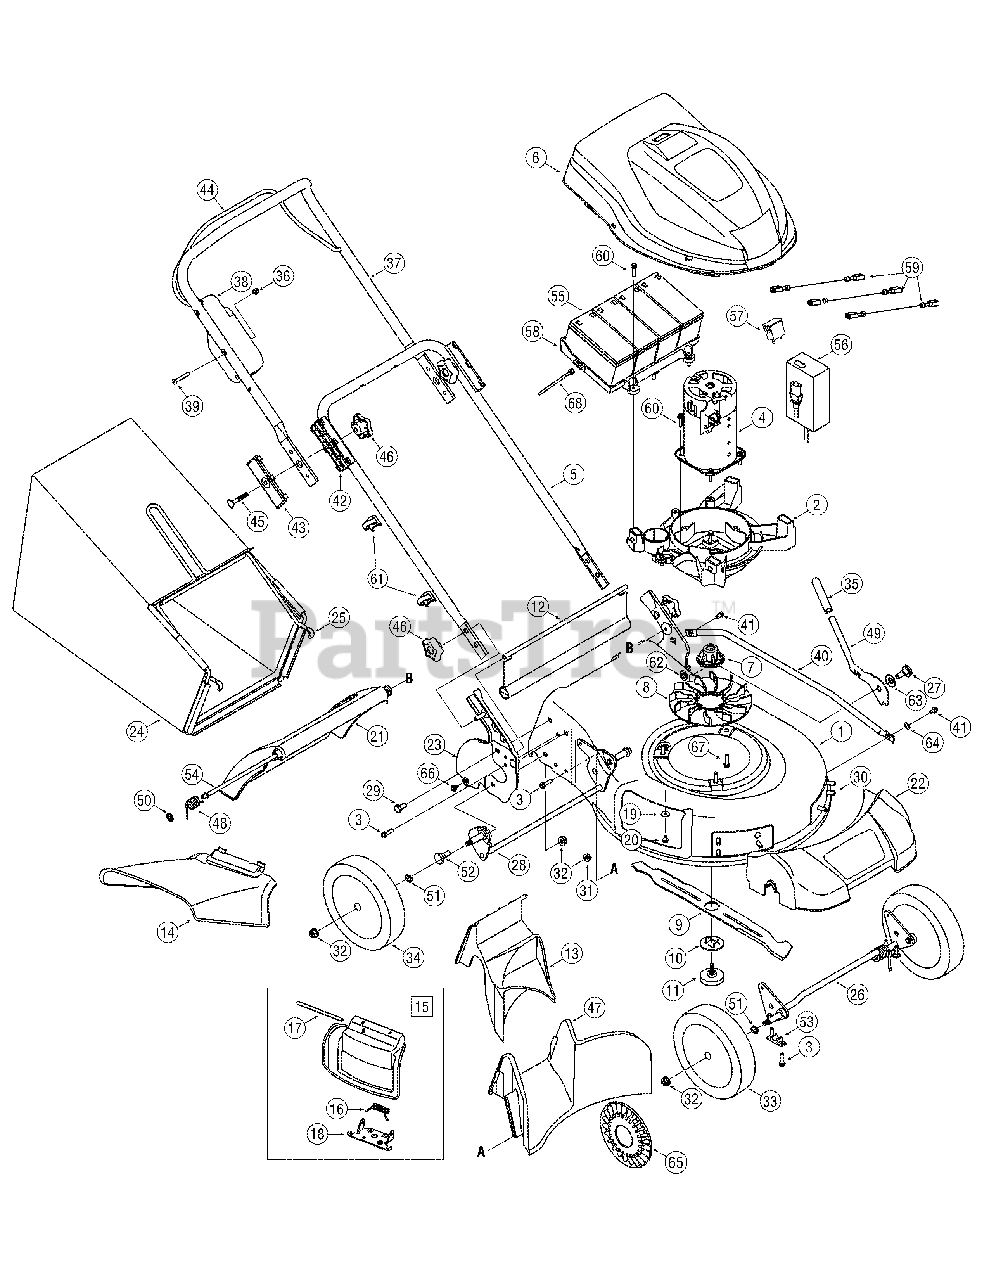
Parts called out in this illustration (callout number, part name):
1	19" Deck
2	Motor Bracket
3	Screw, 1/4-15 x 1.000
4	Motor, 48V
6	Battery Shroud
7	Blade Hub
8	Electric Fan
9	Mulching Blade
10	Blade Locking Plate
11	Blade Bolt Assembly
12	Trail Shield
13	Rear Mulch Plug
14	Side Discharge Chute
15	Mulch Plug (Incl. 16-18)
16	Torsion Spring
17	Hinge Pin
18	Chute Deflector Adapter
19	Beleville Washer
20	Screw
21	Rear Door
22	Front Cover
23	Handle Bracket - RH
23	Handle Bracket - LH
24	Grass Bag
25	Grass Bag Frame
26	Front Bracket Assembly
27	Screw, Shoulder, .50 x .66
28	Rear Bracket Assembly
29	Hhcs, 5/16-18 x .625
30	Screw, 5/16-14 x .750
31	Nut, Flange Lock, 5/16-18
32	Nut, Flange Lock, 3/8-16
33	Front Wheel
34	Rear Wheel
35	Foam Grip
36	Nut, Hex Lock, 1/4-20
37	Upper Handle
38	Motor/Blade Control
39	Screw, Flat, 1/4-20 x 1.75
40	Cross Bracket
41	Screw, Shldr., 1/4-20 x .50
42	Lower Handle Insulator
43	Upper Handle Insulator
44	Motor/Blade Control Handle
45	Bolt Carriage, 5/16-18 x 2.50
46	Star Knob
47	Rear Baffle
48	Door Torsion Spring - RH
48	Door Torsion Spring - LH
49	Spring Lever
50	Nut, Speed
51	Washer, Wave, .510 x .750 x .017
52	Screw, Shoulder, .500 Dia. X .434
53	Bushing, Block, .505 Dia. X .62
54	Rear Door Pivot Rod
55	Battery, 12V
56	Battery Charger
57	Battery Level Indicator
58	Battery Tray
59	Battery Jumper
60	Screw, 1/4-15 x .750
61	Cable Guide
62	Spacer, .515 x 1.00 x .310 Lg.
63	Washer, Bell, .510 x 1.14 x .040
64	Washer, Wave, .390 x .825 x .016
65	Hubcap
66	Screw, #10-16 x .375
67	Screw, 5/16-12 x .750
68	Cable Tie
